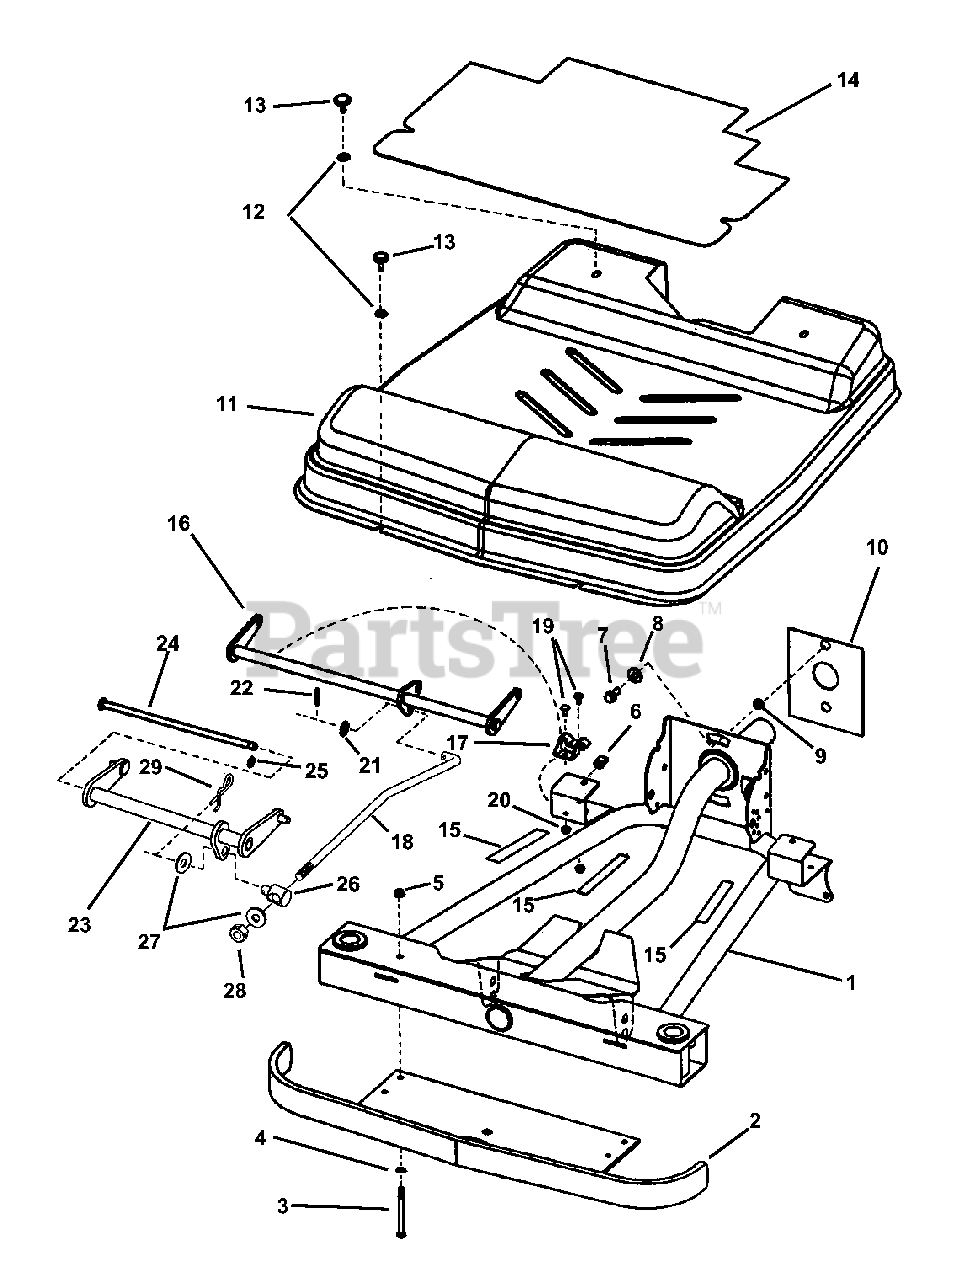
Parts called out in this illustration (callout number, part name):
1	WELDMENT, Front Frame
2	WELDMENT, Front Bumper
3	BOLT, 5/16-18 x 3-3/4" Hex Cap
4	WASHER, 5/16" Split Lock
5	NUT, 5/16-18 Hex Flange Lock, Grade 5
6	FASTENER, "U" Type 1/4"-20
7	SCREW, 3/8-16 x 1" Hex Washer Face, Self-Tap
8	WASHER, 3/8" Flat (was 90517)
9	SPACER, Front Frame Pivot
10	PLATE, Front Frame Pivot
11	FLOOR, Front Frame
12	WASHER, 1/4" Internal/External Lock
14	FLOOR MAT
15	PAD, Floor Pan
16	WELDMENT, Rear Lift
17	BRACKET, Saddle
18	ROD, Timing
19	BOLT, 1/4-20 x 5/8" Short Square Neck Carriage
20	NUT, 1/4-20 Flange Lock
21	WASHER, 1/2" Flat
22	PIN, 1/8 x 1" Cotter
23	WELDMENT, Front Lift
24	ROD, Deck Support
25	RING, .438 External Retaining
26	SWIVEL
27	WASHER, 1/2 Flat
28	NUT, 1/2-13 Hex
29	PIN, 1/8 x 1/2" Locking Hair
